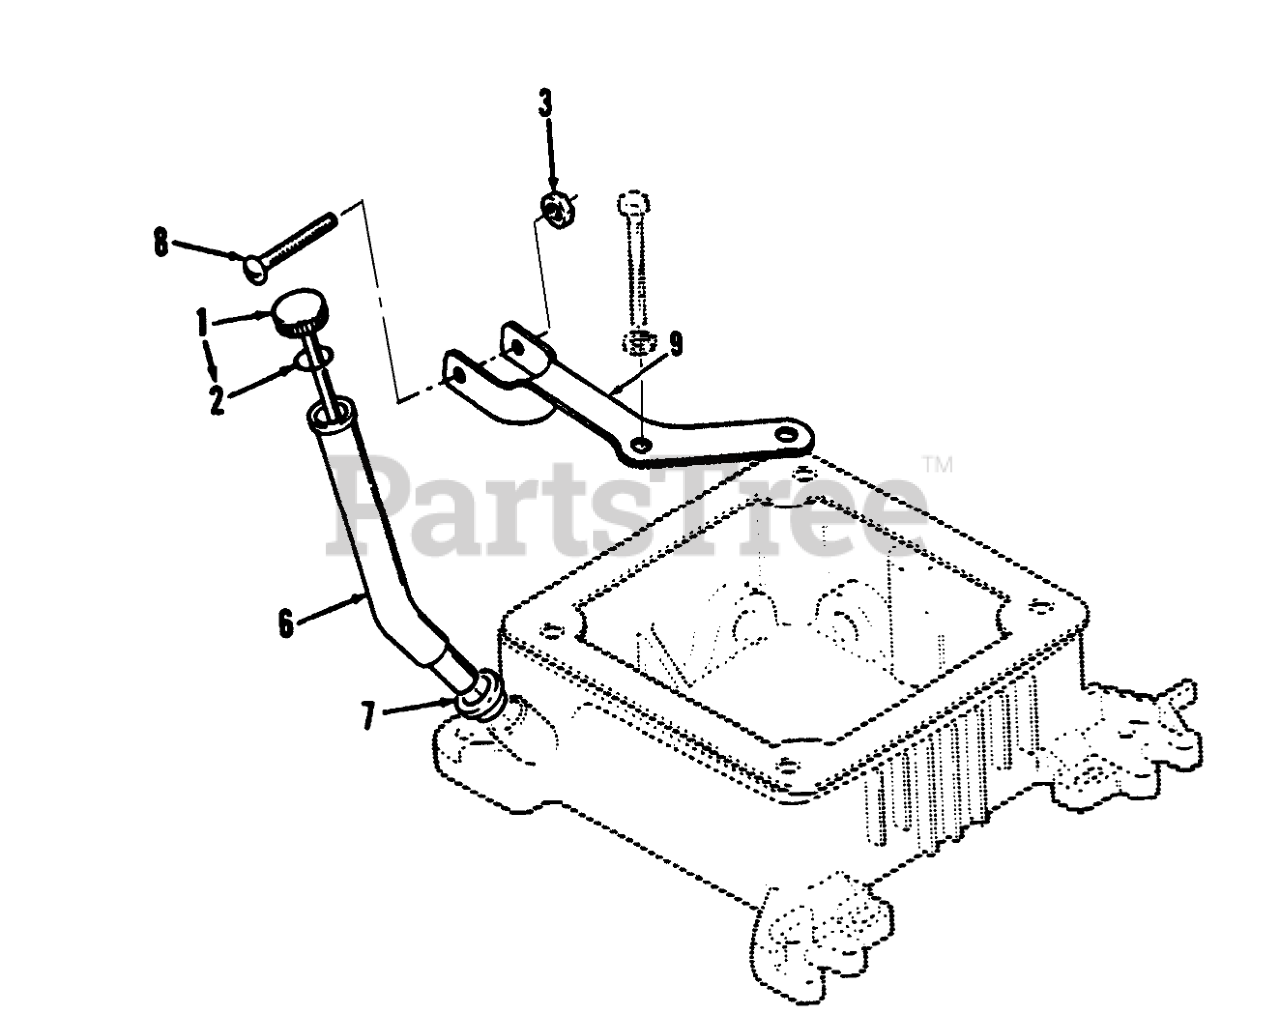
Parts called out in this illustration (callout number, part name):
1	Cap & Indicator-Oil Fill (Includes O-Ring) Dipstick-1.75 Quart Capacity Specifies Pints-16.27" Long
2	O-Ring
3	NUT - SPEED
6	Tube-Oil Fill
7	Seal
8	SCREW - PAN HEAD
9	BRACKET-FILL TUBE
